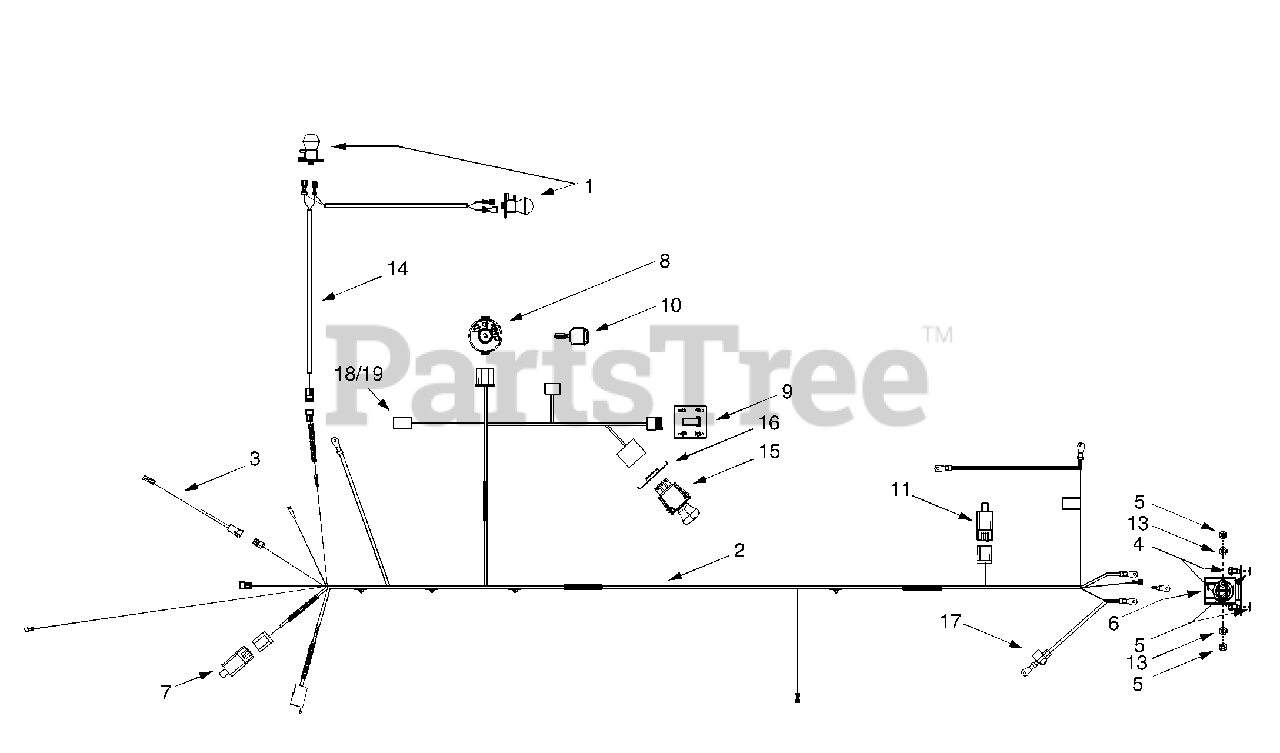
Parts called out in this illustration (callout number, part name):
1	Bulb/Socket Headlight Assembly
2	Wiring Harness w/o Ref. 14
3	Harness Adapter, #18 x 5
4	Self Tapping Screw, 1/4-20 x .5
5	Hex Nut, 1/4-20
6	Solenoid, 12-volt, 100 Amp
7	Snap Mt. Safety Interlock Switch (Brake)
8	Ignition Switch
9	Indicator Monitor / Hour Meter
10	Ignition Key
11	Safety Plunger Switch (Seat)
13	Lock Washer, 1/4
14	Headlight Harness
15	Electric PTO Switch
16	Retainer Bracket
17	Positive Terminal Cover (Boot)
18	Fuse Holder
19	20-amp Fuse
